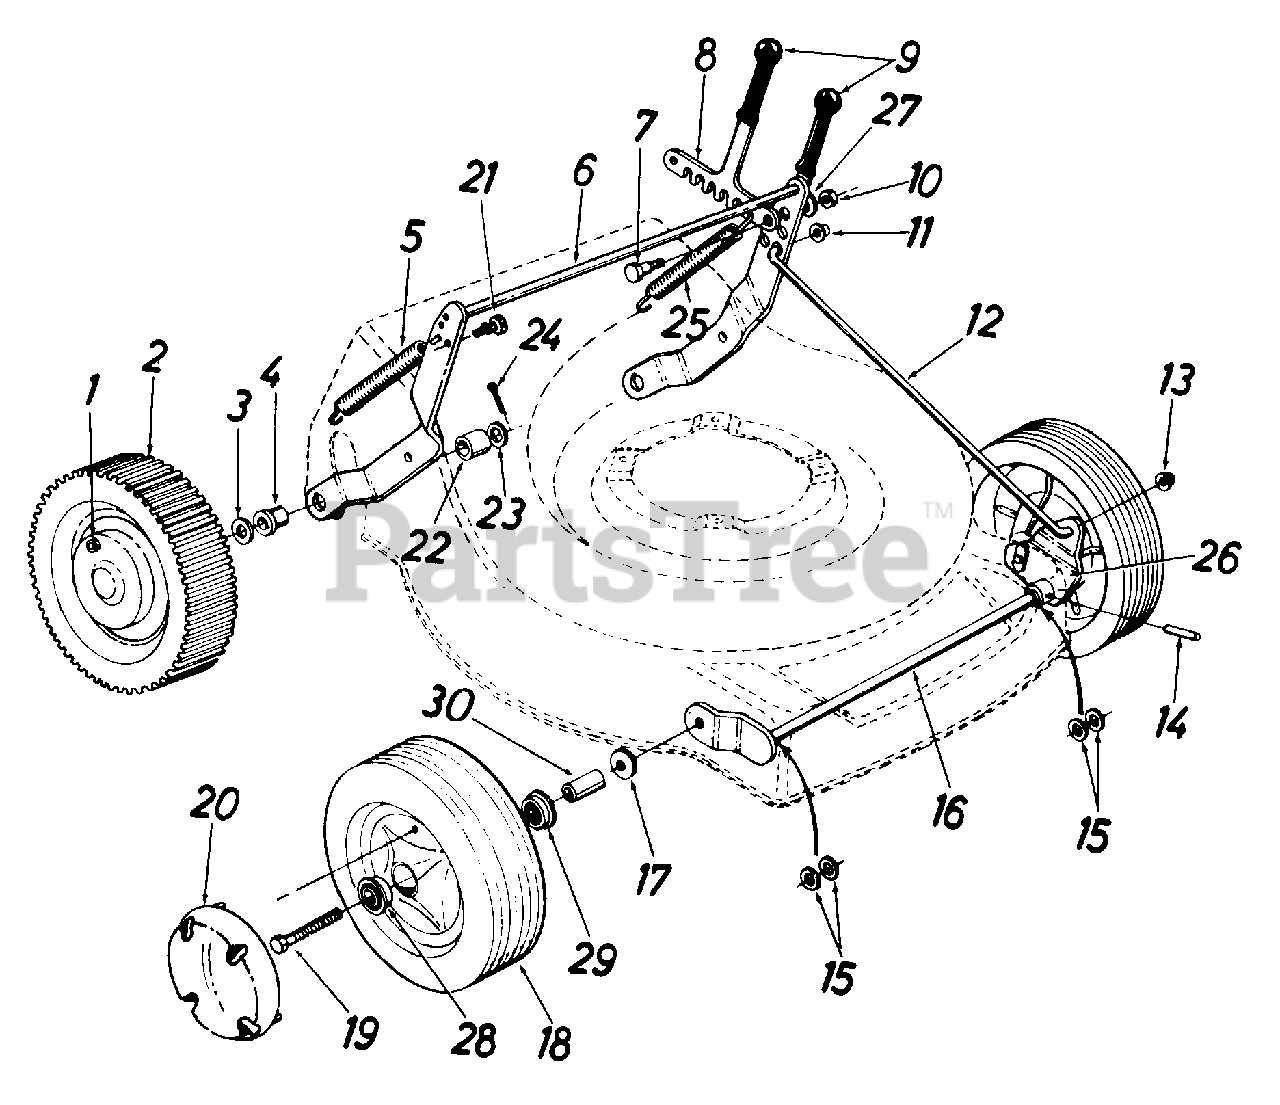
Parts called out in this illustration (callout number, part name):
1	Hex Ins. L-Nut 1/4-20 Thd.
2	Rear Wheel Ass'y.
3	Fl-Wash. .510 I.D. x .930 O.D.
4	Flange Brg. .506 I.D.
5	Extension Spring .50 O.D. x 4.25
6	Rear Wheel Pivot Brkt. Ass'y.
7	Shld. Bolt. .437 Dia. x .180
8	Height Adjusting Lever
9	Grip Black
10	Hex Nut 5/16-18 Thd.
11	Push Cap 5/16" Rod
12	Linkage Rod .31 O.D. x 23.25" Lg.
13	Push Cap 5/16" Rod
14	Spring Pin Roll 3/16" Dia. x 1.00" Lg.
15	Fl-Wash. .510 I.D. x 1.00 O.D.
16	Wheel Axle Brkt. Ass'y.
17	Bell-Wash. .400 I.D. x .88 O.D. x .060
18	Front Wheel Ass'y. Comp.
19	Hex Scr. 3/8-16 x 2.00" Lg.
21	Rubber Bumper
22	Spacer .70 I.D. x .88 O.D. x 1.00" Lg.
23	Fl-Wash. .510 I.D. x .930 O.D. x .050
24	Cotter Pin 3/32" Dia. x 1.00" Lg.
25	Extension Spring .50 O.D. x 4.25
26	Front Wheel Brkt. Ass'y.
27	L-Wash. 5/16" Scr.
28	Ball Bearing 3/8" I.D.
29	Ball Bearing 1/2" I.D.
30	Spacer 3/8" I.D.
